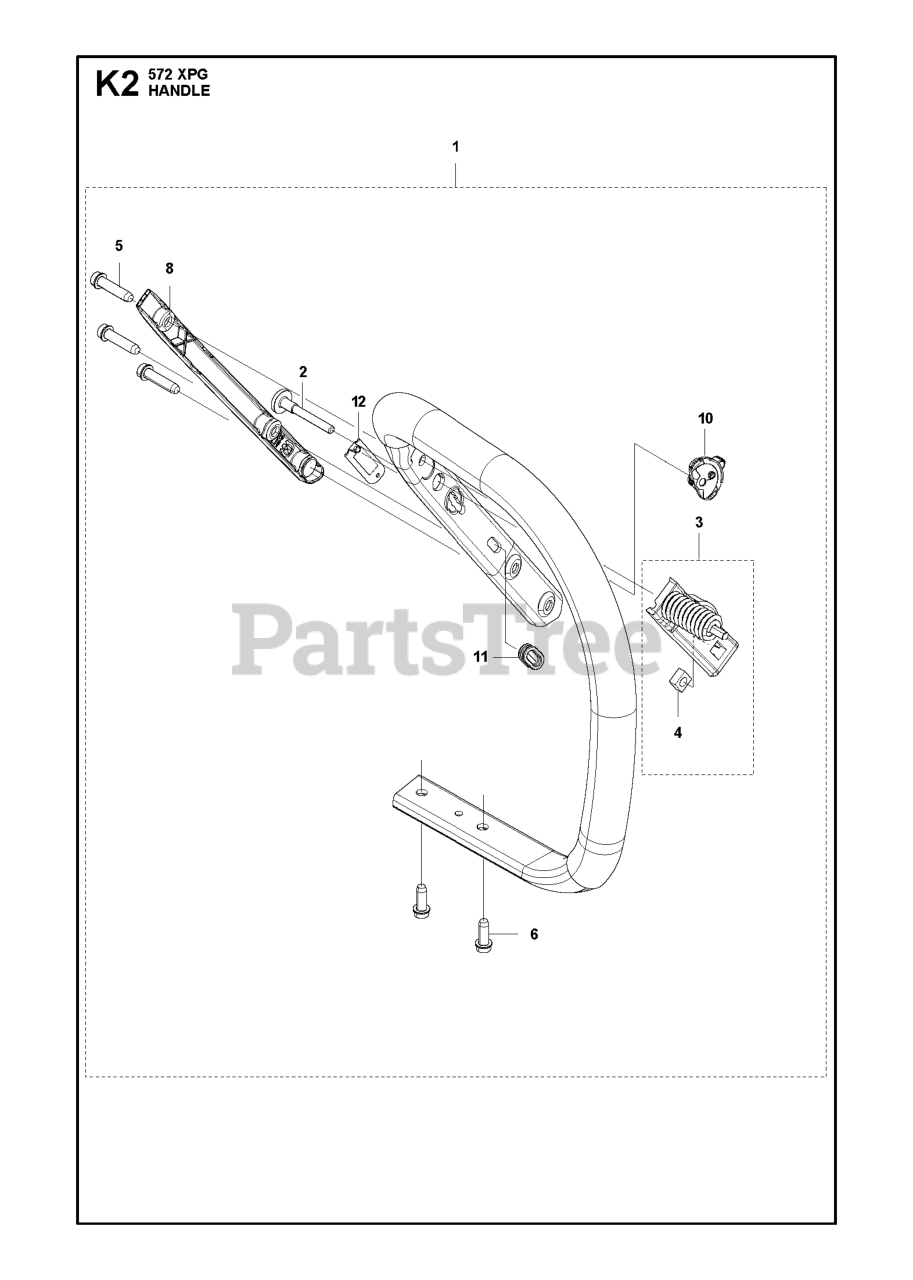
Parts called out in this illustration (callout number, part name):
1	FRONT HANDLE ASSY KIT HEATED -
2	SCREW ITXPANM MOVEMENT LIMITER
3	ANTIVIBRATION ELEMENT ASSY HEA
3	ANTIVIBRATION ELEMENT ASSY HAR
8	COVER FRONT HANDLE HEAT
12	PROTECTION FRONT HANDLE, HEAT
